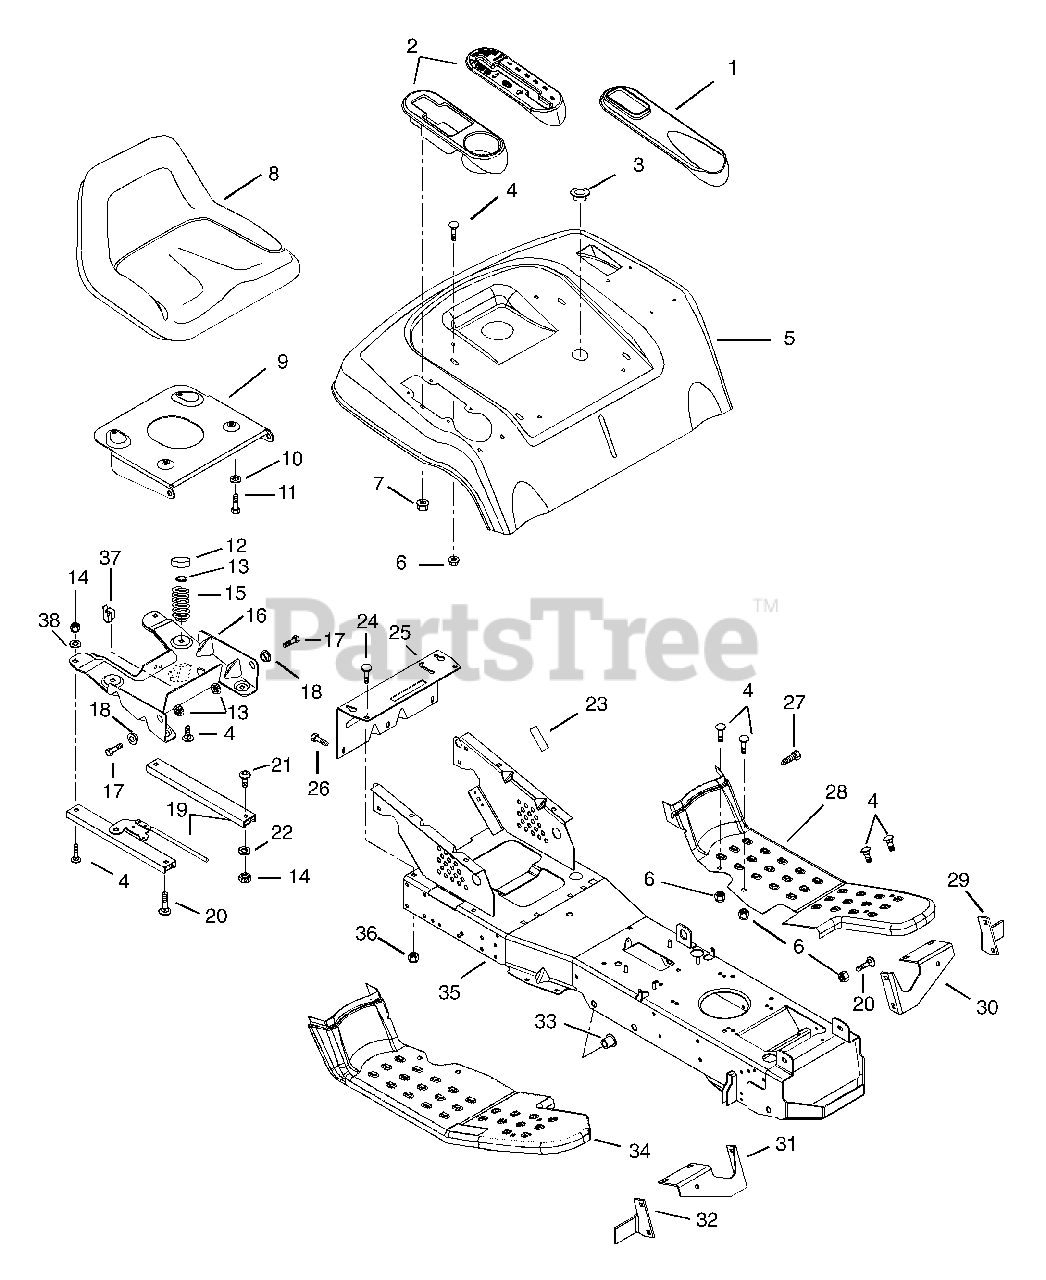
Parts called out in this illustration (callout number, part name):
1	INSERT- LIFT
2	INSERT- SHIFT
2	INSERT - BEVERAGE
3	SNAP BUSHING
4	@BLT-RHDSSQNK .31-18X.62 G5YZ
5	REAR DECK
6	@NUT-SPNLK-FLG .312-18 YWZC
7	NUT-SELF-THRDNG FITS.25 STUDPL
8	SEAT- V1400
8	SEAT
9	SEAT PIVOT PLATE
10	WSHR-LK .312X.097 HVY YWZC
11	@BLT-HEX .31-18X.75 GR5 YWZC
12	TUBE CAP
13	@NUT-LK-CTR .31-18 YWZC
14	@NUT-HEX .31-18 YWZC
15	SG-COMP .148X1.23X2.41 WLD87
16	BOX, SEAT
17	@BLT-HEX .31-18X.75 GR5 YWZC
18	BSHG-FLG .325X.465X.333X.685
19	SEAT SLIDES -(RAME TAK-3010-4)
20	BLT-RDHDSQSHK.31-18X.75 GR2 YW
21	SCR-CAP BTHD.31-18X.50 GR5 YZ
22	WSHR-LK-INT .313X.030 PL
23	PAD,BATTERY
24	@BLT-RDHDSQNK .38-16X.75 G2YWZ
25	DRAW BAR
26	@SCR-TAP .31-18X.75 HWH TR YWZ
27	@SCR-TAP .31-18X.50 HWH TR YWZ
28	FOOT REST L.H.
29	BRACKET - MOWER HEIGHT L.H.
30	BRACE - FOOT REST L.H.
31	BRACE - FOOT REST R.H.
32	BRACKET - MOWER HEIGHT R.H.
33	BSHG-FLG .515X.750X.745X1.00NY
34	FOOT REST RH
34	FOOTREST- R GEAR
35	FRAME, MAIN
36	@NUT-LK-CTR .38-16 YWZC
37	CLIP-HARNESS TINNERMAN
38	@WSHR-LK .31X.078 REG YWZC
